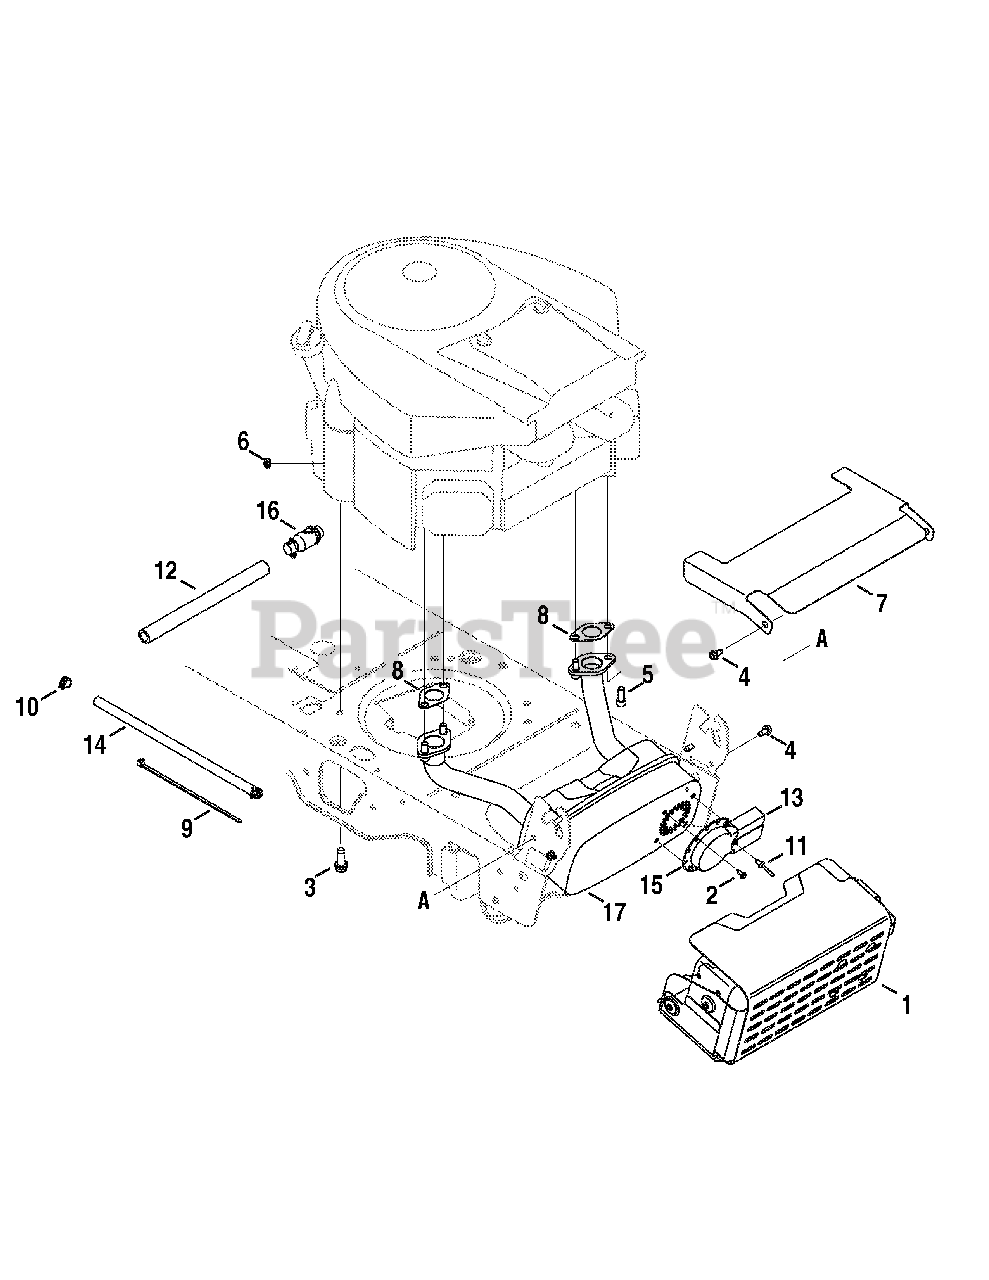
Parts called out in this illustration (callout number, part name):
1	Mulffler Shield Assembly
2	Screw, Indented Washer, #8-18:0.500
3	Taptite Screw, Indented Washer, 3/8-16:1.000
4	Taptite Screw, Indented Washer, 1/4-20:0.500
5	Socket Head Screw, 5/16-18:.750
6	Sems Nut, 1/4-20
7	Heat Shield
8	Exhaust Gasket
9	Cable Tie, 3/16 X .05 X 7.4
10	Hose Clamp, .490 DIA.
11	Rivet, .188 DIA X .300 L
12	Oil Drain Extension Hose
13	Muffler Deflector
14	Fuel Hose
15	Long Muffler Deflector
16	Oil Drain
17	Muffler Deflector
